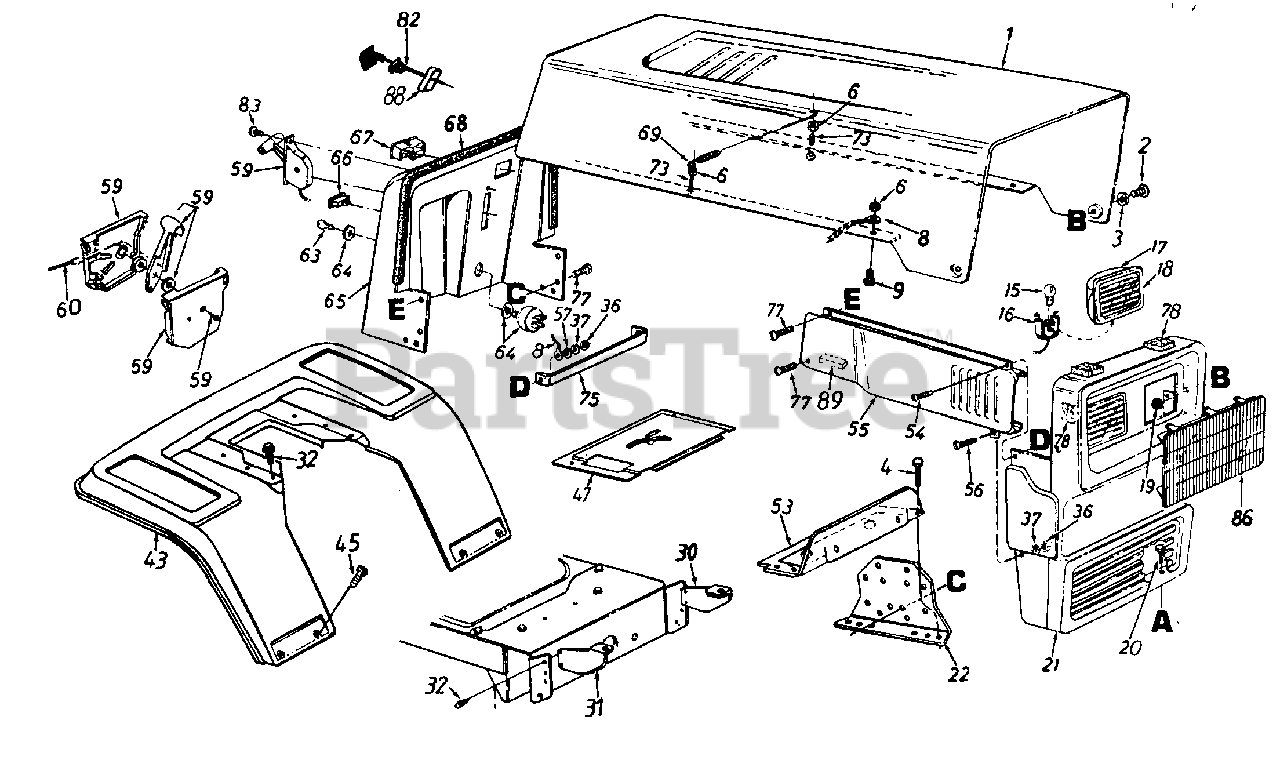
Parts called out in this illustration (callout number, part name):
3	Washer .39" I.D. x .62"
4	Hex Wash. Hd. B-Tap Scr. 5/16-18 x .5" Lg.
6	Hex Sems Nut #10-24 Thd.
8	Hood Stop
9	Truss Hd. Scr. #10-24 x 1/2"
15	Lamp
16	Twist Lock-Lamp Socket
17	Headlight Housing
18	Lens
19	L-Nut 1/4-28 Thd.
20	Hex Bolt 5/16-18 x .75" Lg.
30	Grille Mount Brk't.-L.H.
36	Hex Nut 1/4-20 Thd.
37	L-Wash. 1/4" I.D.
47	Transmission Panel
53	Fuel Tank Support
54	Truss Hd. Scr. 1/4-20 x .75"
55	Side Cover-R.H.
57	Fl-Wash. .281" I.D. x .73" O.D.
59	Throttle Control Box Ass'y.
60	Throttle Control Wire
63	Ignition Key
64	Ignition Switch
67	Ammeter
68	Trim Strip-31"
69	Hood Spring
73	Hex Scr. #10-24 x 1.0" Lg.
75	Tie Strap-Grille/Side Panel
77	Hex Wash. Hd. Tap Scr. 1/4 x .75" Lg.
78	Foam Strip 3/8 x 1-1/8" x 1-1/2" Lg.
82	Choke Control 29" Lg.
83	Truss Mach. AB-Tap Scr. #10 x .5" Lg.
86	Headlight Bezel
88	Choke Retainer
89	Rubber Strip
